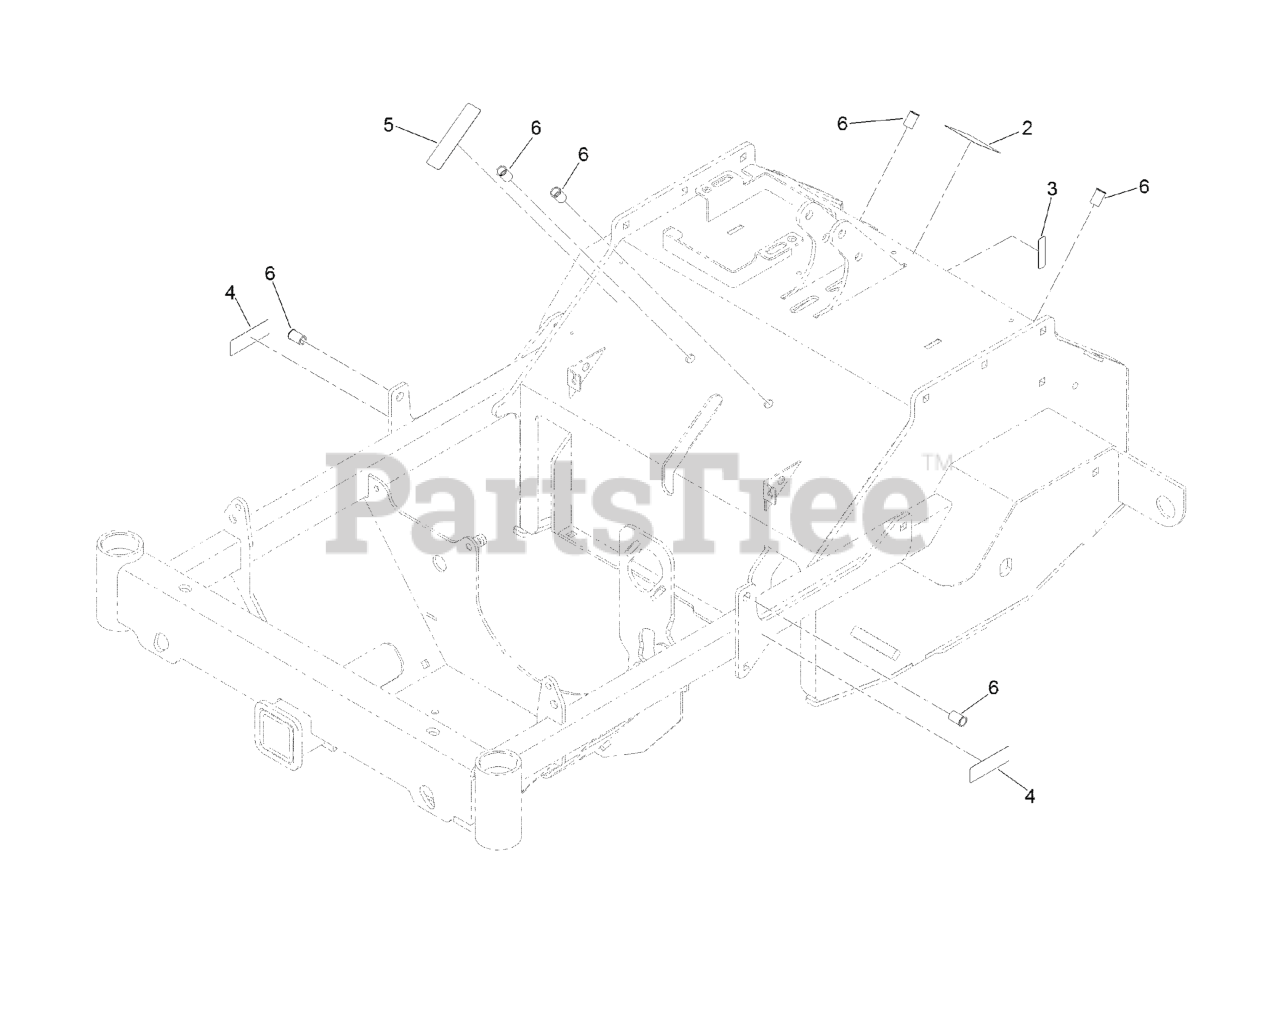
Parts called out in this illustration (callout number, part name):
2	DECAL-WARNING
3	DECAL-WARNING
4	DECAL-DANGER
5	DECAL-ARRESTER, SPARK
6	NUT-CLINCH
